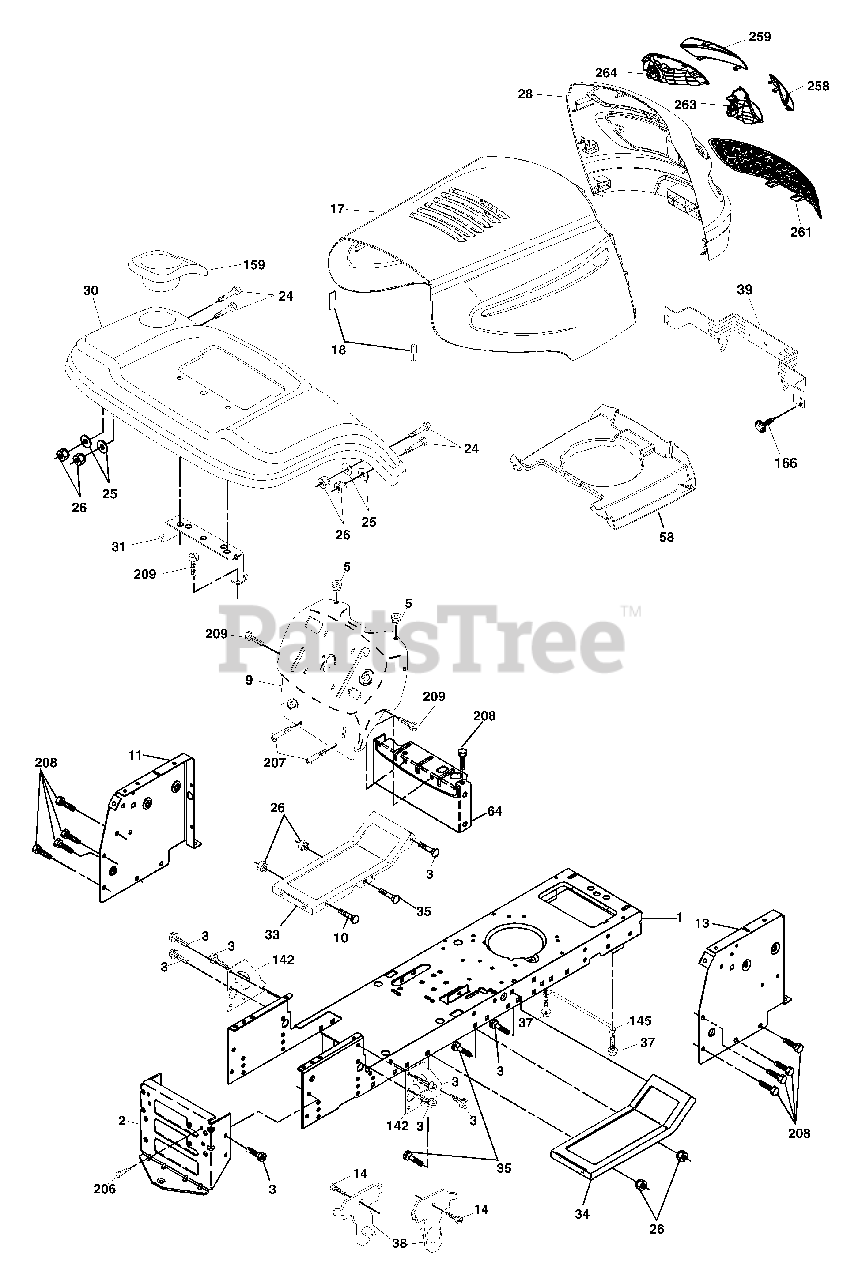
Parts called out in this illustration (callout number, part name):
1	Chassis
2	Drawbar
3	Screw 3/8-16 x 3/4
5	Bumper Hood/Dash
9	Dash
10	Bolt Rd Hd Sqnk. 3/8-16 Unc x 1
11	Panel Asm. Dash Lh
12	Clip Tinnerman Grile P/L
13	Panel Dash Rh
14	Screw Thdrol 3/8-16 x 1/2
17	Hood
18	Bumper Hood
24	Bolt Fin Hex 3/8-16 Unc x 1 Gr. 5
25	Washer 13/32 x 13/16 x 12 Ga.
26	Nut Lock Hex w/Insert 3/8-16 UNC
28	Grill/Lens Asm
30	Fender Asm
31	Bracket Fender
33	Footrest LH
34	Footrest RH
35	Bolt Rd Hd Sht. Sqnk. 3/8-16 x 3/4
37	Screw Thdrol 5/16-18 x 1/2 Tyt
38	Bracket Asm. Pivot Mower Rear
39	Bracket Pivot
58	Air Duct
64	Dash Lower
142	Plate Reinforcement
145	Rod Pivot Chassis/Hood
159	Cupholder
166	Screw #13-16 x 3/4
206	Bolt shoulder 5/16-18
207	Screw Thdrol 5/16-18 x 1/2
208	Screw Thdrol 3/8-16 x 1/2
209	Screw 3/8-16 x 3/4
258	Lens Grille RH
259	Lens Grille LH
263	Bezel Grille LH
264	Bezel Grille RH
